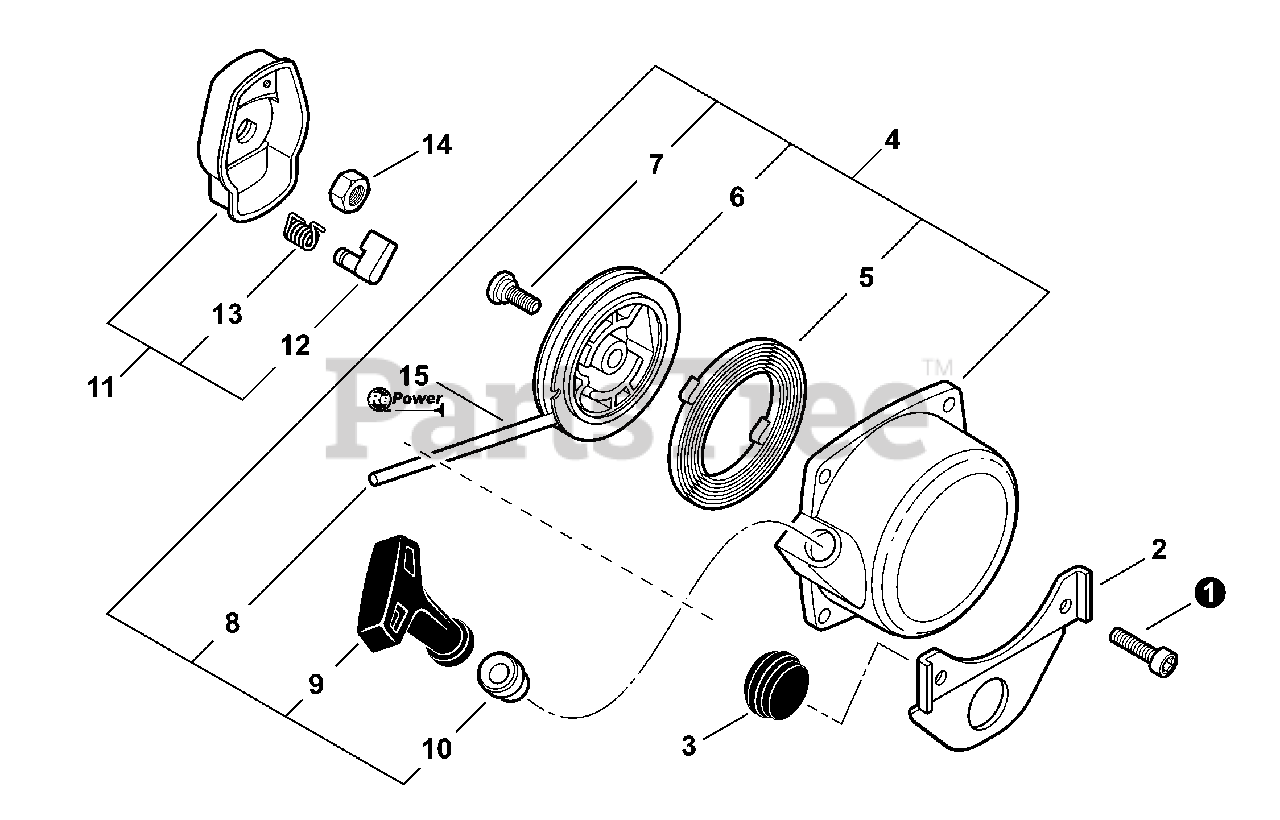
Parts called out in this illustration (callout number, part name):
1	SCREW - 4×16
2	BRACKET, FUEL TANK
3	CUSHION
4	STARTER ASSY
5	SPRING, REWIND
6	REEL, ROPE
8	ROPE, STARTER - 3×1000
9	GRIP, STARTER
10	GUIDE, ROPE
11	STARTER PAWL ASSY
12	PAWL, STARTER - BLACK
13	SPRING, RETURN
15	ROPE, STARTER - REPOWER BULK
